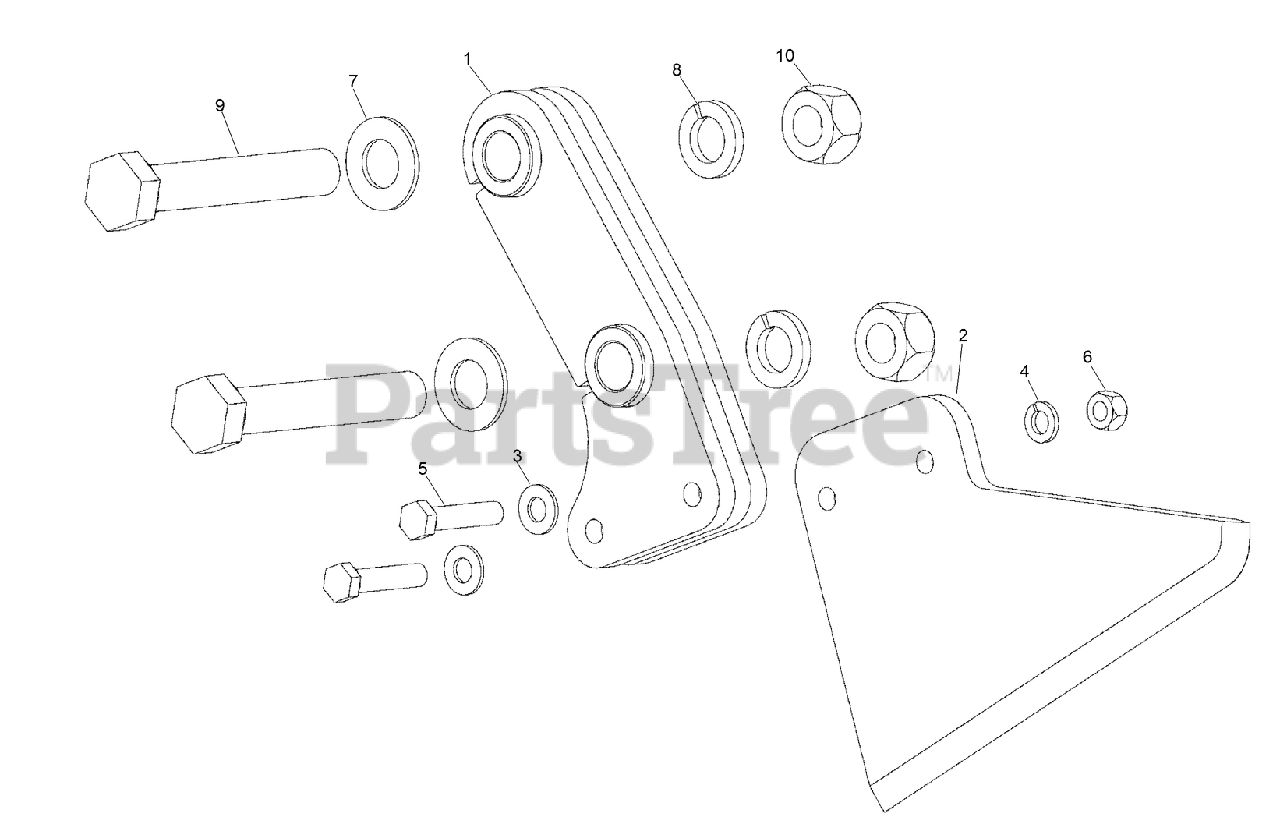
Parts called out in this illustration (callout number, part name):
1	WELDMENT - Sod Cutter Mount
2	PLATE - Sod Cutter Blade
3	WASHER-0.531 x 1.062 x 0.092 in CST ZND
4	WASHER-Spring Lock Reg 1/2 ZND
5	BOLT-Hex Hd 0.500 x 2.25 GR8 ZND
6	NUT-Hex 0.500-13 GR5 ZND
7	WASHER-FLAT
8	WASHER - Spring Lock, Reg 1.000 in ZND
9	BOLT-HH
10	NUT - Hex, 1.00 x 8 GR5 ZND
